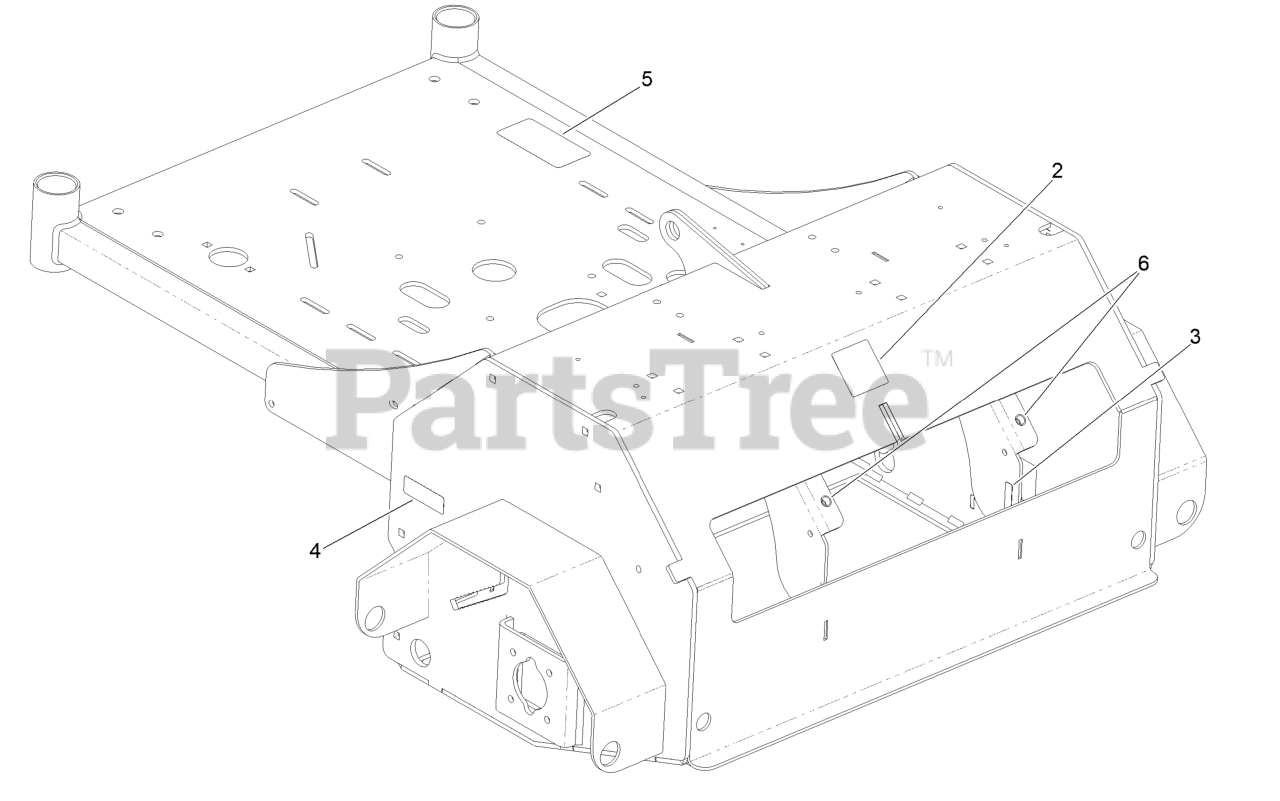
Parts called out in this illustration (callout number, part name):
2	Decal-Warning
3	Decal-Warning
4	Decal-Danger
5	Decal-Belt Routing
6	Insert-Nut
